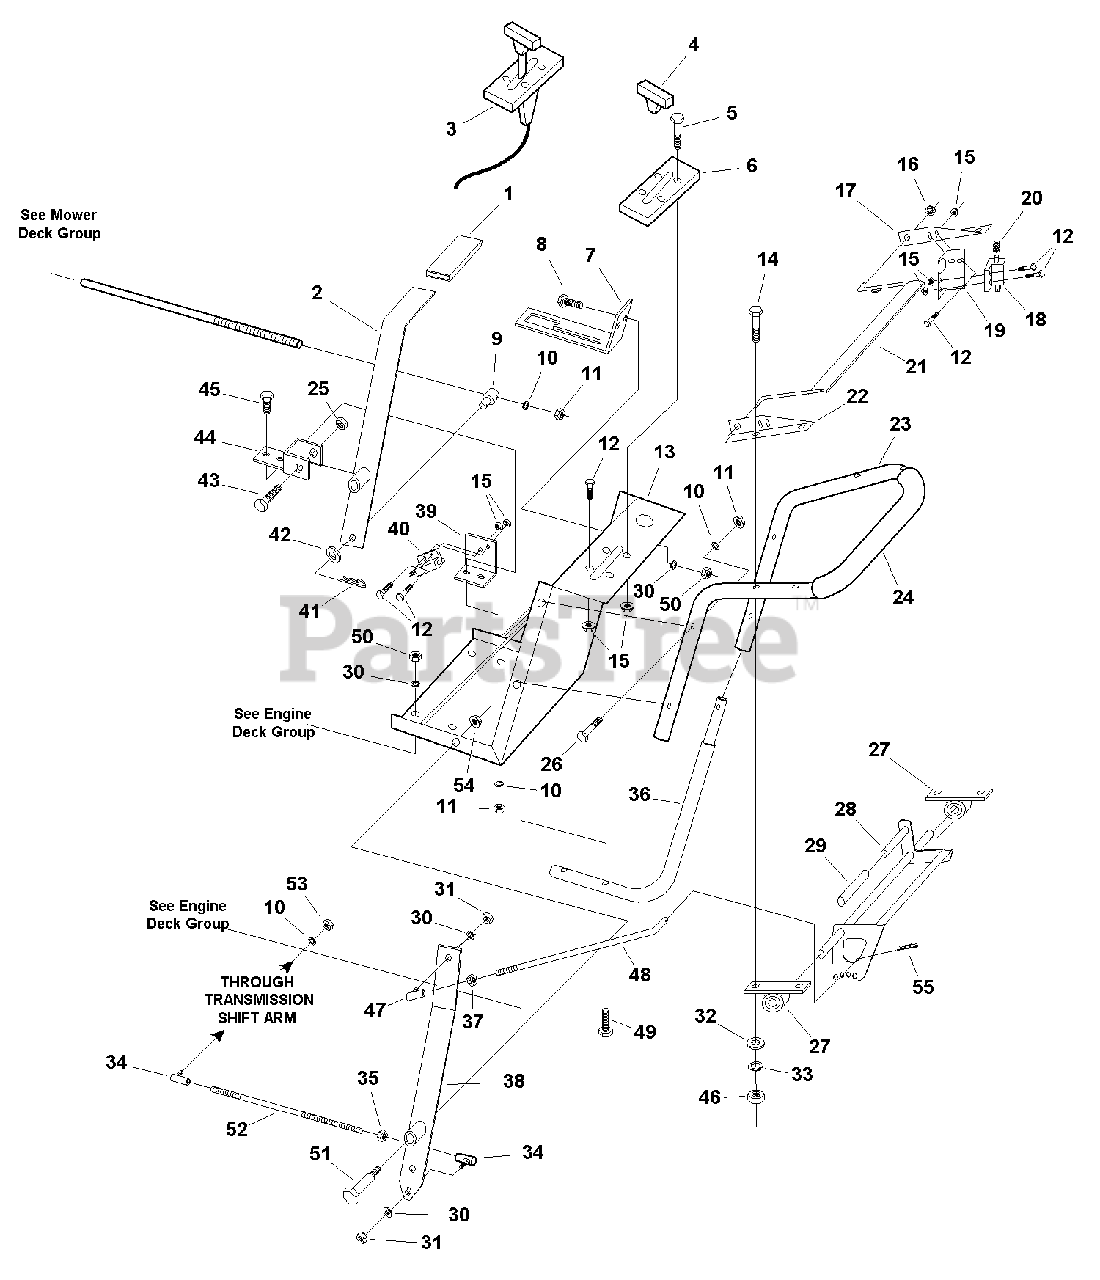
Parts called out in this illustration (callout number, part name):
1	Handle grip
2	Blade Clutch Engagement Lever
3	Throttle Control Cable Assembly, 13 HP Honda
3	Throttle Control Cable Assembly, 15 HP Kawasaki
3	Throttle Control Cable assembly, 9 HP Briggs
4	Throttle Control, T-Handle
5	Rivet, 3/16
6	Throttle Speed Indicator Plate
7	Blade Engage Lever Lock Bracket
8	Capscrew, Hex Head, 3/8-16 x 1
9	Rod, Fitting End
10	Lockwasher, 5/16
11	Nut, Hex, 5/16-18
12	Screw, 8-32 x 3/4
13	Control Deck & Dash Panel
14	Capscrew, Hex Head, 1/4-20 x 1-3/4
15	Nut Assembly, 8-32
16	Push Nut, 5/16
17	Safety Bar Pivot Bracket, Left
18	Safety Switch
19	Safety Switch Mounting Bracket
20	Safety switch return spring
22	Safety Bar Pivot Bracket, Right
23	Upper Handle
24	Foam Handle Cover
25	Nut, Hex Flangelock, 1/2-13
26	Capscrew, Hex Head, 5/16-18 x 1-1/2
27	Bearing, 3/4 ID
28	Drive Engagement Bar
29	Handle, Grip, Reverse
30	Lockwasher, 3/8
31	Nut, Jam, 3/8-24
32	Flatwasher, 1/4
33	Lockwasher, 1/4
34	Ball Joint, 5/16-24
35	Nut, Hex Jam, 3/8-24, LH
36	Lower Handle
37	Nut, Jam, 3/8-24
38	Transmission Drive Intermediate Lever
39	Deck Safety Switch Bracket
40	Deck Safety Switch
41	Bridge Pin, #2
42	Washer, 3/8
43	Capscrew, Hex Head, 1/2 x 2-1/2
44	Blade Clutch Engagement Lever Bracket
45	Capscrew, Hex Head, 5/16-18 x 1
46	Nut, Hex, 1/4-20
47	Ball Joint, 3/8-24 RH
48	Transmission Engagement Rod, Upper
49	Capscrew, Hex Head, 5/16-18 x 1-3/4
50	Nut, 3/8-16
51	Bolt, Shoulder, 1/2 x 1 -3/8 to 3/8-16
52	Transmission Engagement Rod, Lower
53	Nut, Hex Jam, 5/16-24
54	Nut, Hex Centerlock, 3/8-16
55	Clip, Hair Pin
